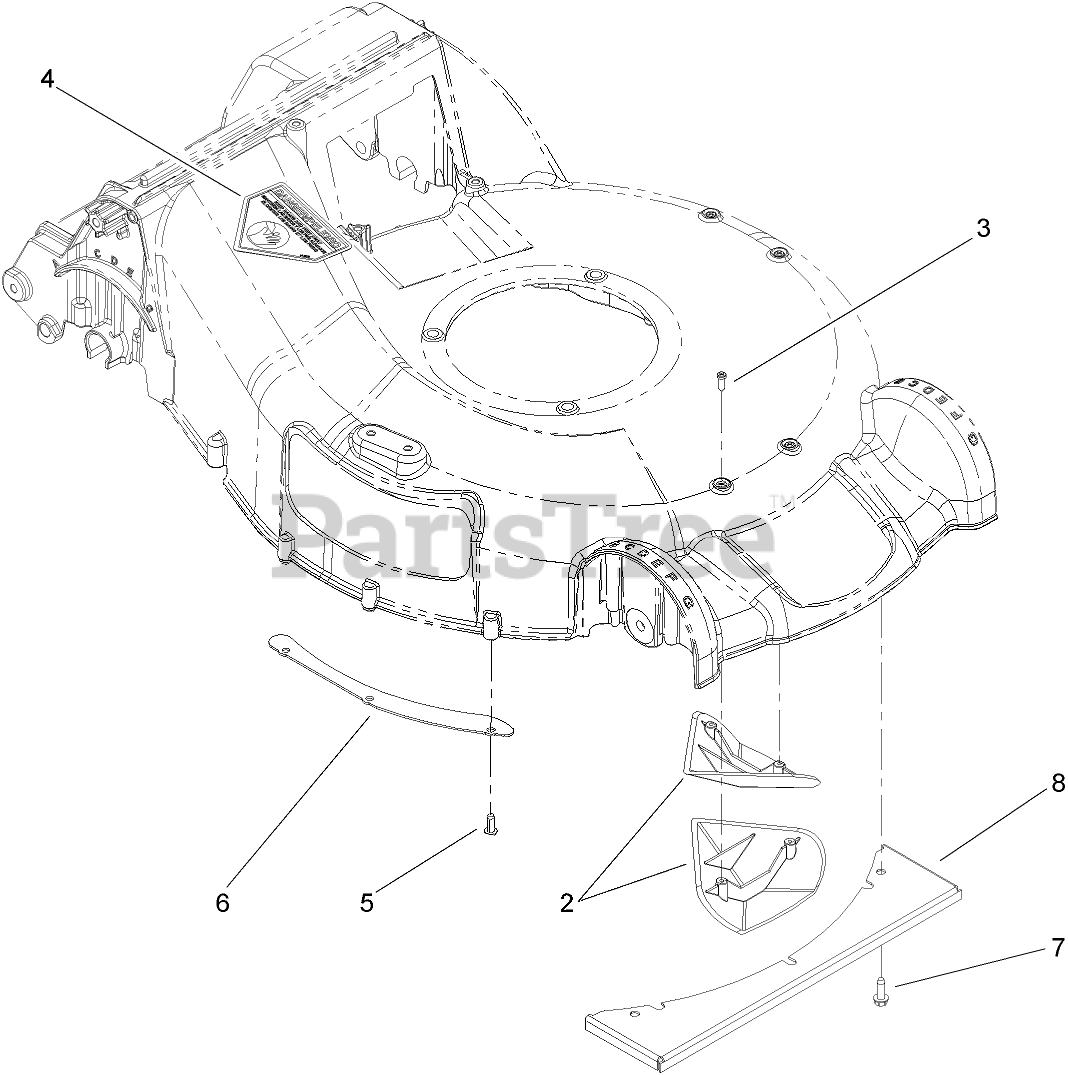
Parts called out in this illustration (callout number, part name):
2	KICKER-HOUSING
3	SCREW-PPH
4	DECAL-DANGER
5	SCREW
6	SHEET-LIP
7	SCREW-HWHTF
8	PLATE-COVER, FRONT
